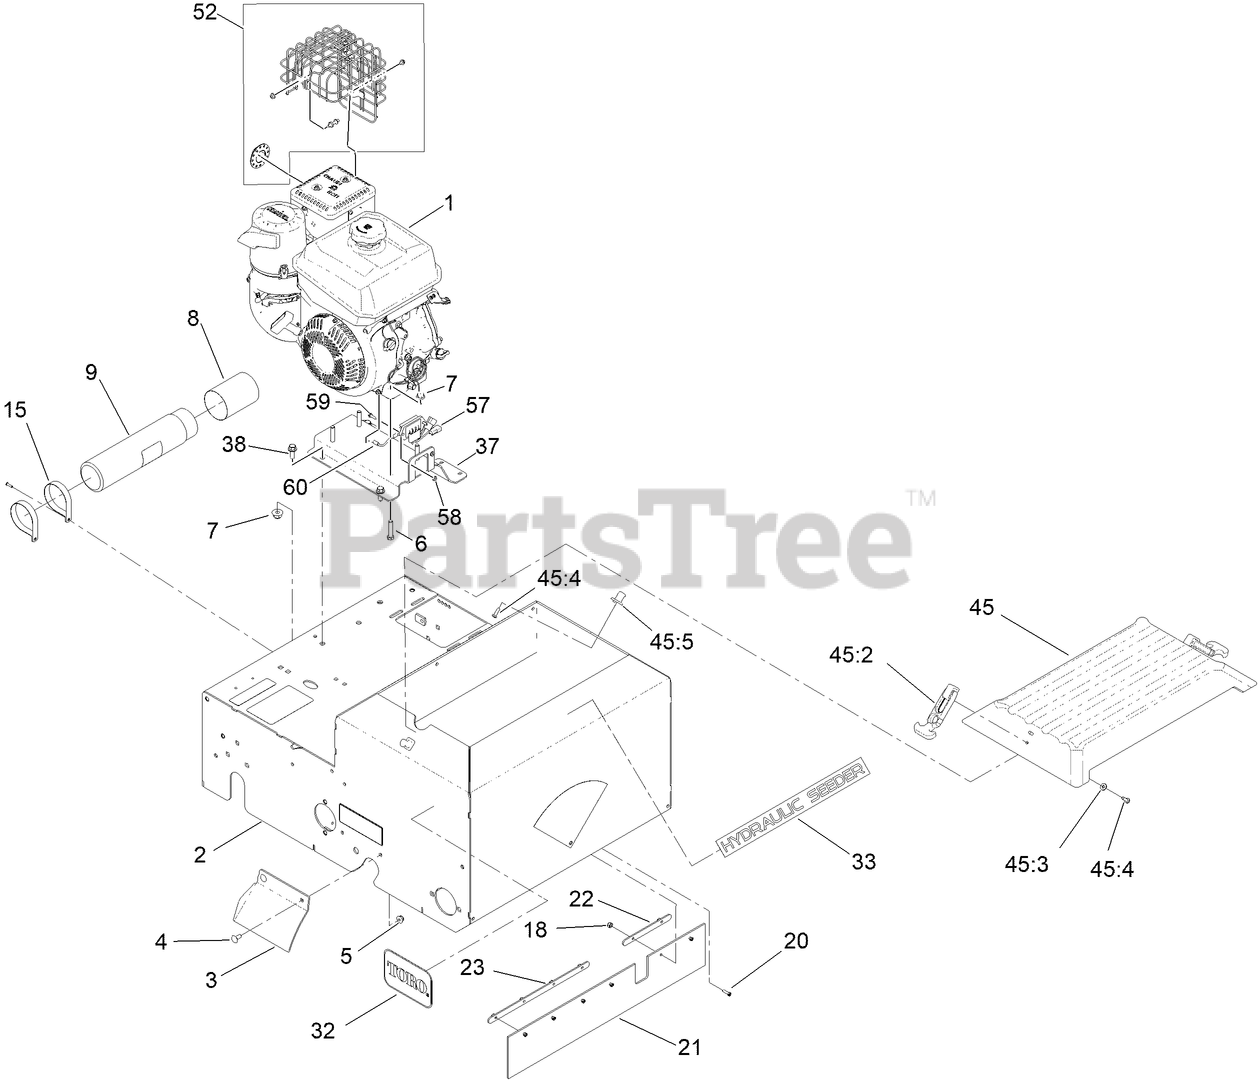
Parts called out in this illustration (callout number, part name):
2	FRAME ASM
3	GUARD-RH
4	SCREW-CARR
5	NUT-HF
6	SCREW-HH
7	NUT-HF, NI
8	CAP-HOUSING
9	TUBE-MANUAL
15	CLAMP-R
18	NUT-LOCK
20	SCREW-SHH
21	GUARD-DUST
22	PLATE-RETAINER
23	PLATE-RETAINER
32	DECAL
37	PLATE-ENGINE
38	SCREW-HHF
45	SEEDER COVER KIT
45:2	LATCH-RUBBER
45:3	WASHER-FLAT
45:4	SCREW-PPH
45:5	LATCH-KEEPER
52	KIT-CH395 MUFFLER GUARD
57	REGULATOR
58	NUT-KEPS
59	SCREW-HWH
60	HARNESS-JUMPER, REGULATOR GROUND
